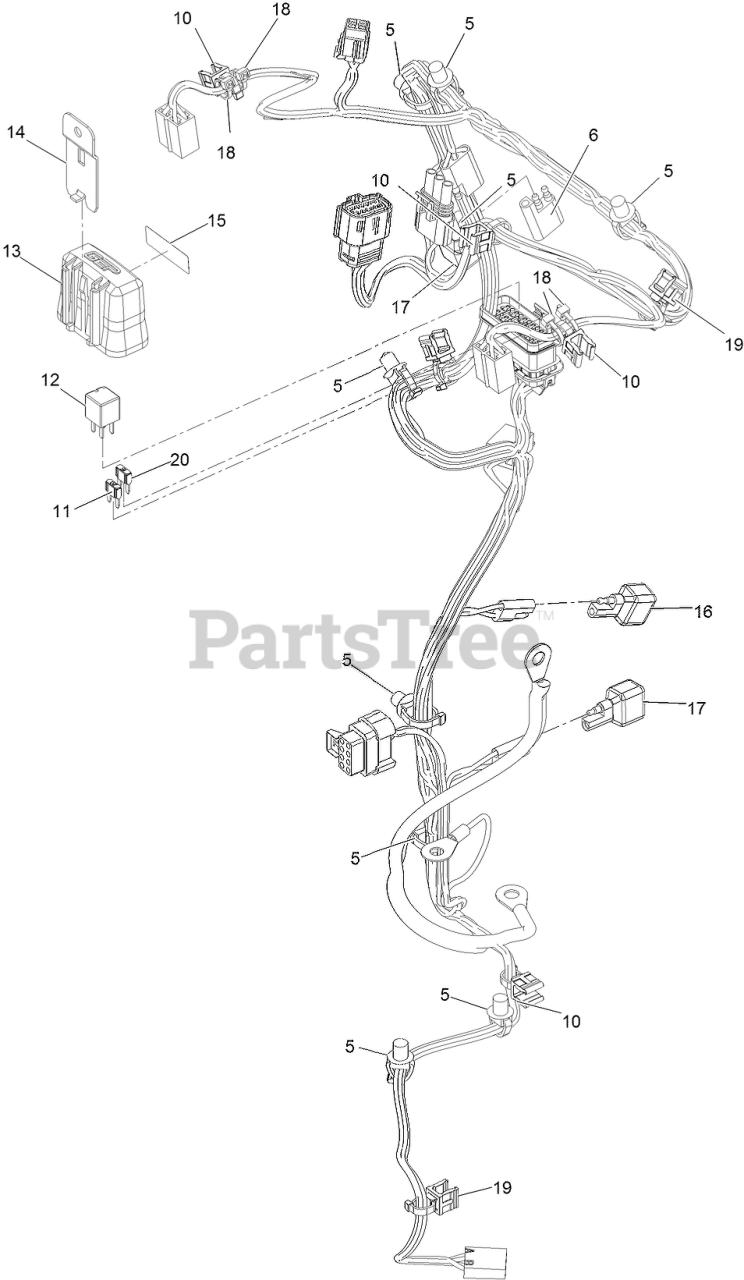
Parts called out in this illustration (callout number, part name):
5	CLIP-TIE
6	Cap-Plug
10	Clip-Edge
11	FUSE-MINI BLADE, 20 AMP
12	RELAY-MICRO
13	COVER-BLOCK, FUSE
14	CLIP-MOUNTING
15	Decal-Fuse
18	TIE-CABLE
19	Clip-Edge W/Tie, Perpendicular
20	FUSE-MINI BLADE, 15 AMP
